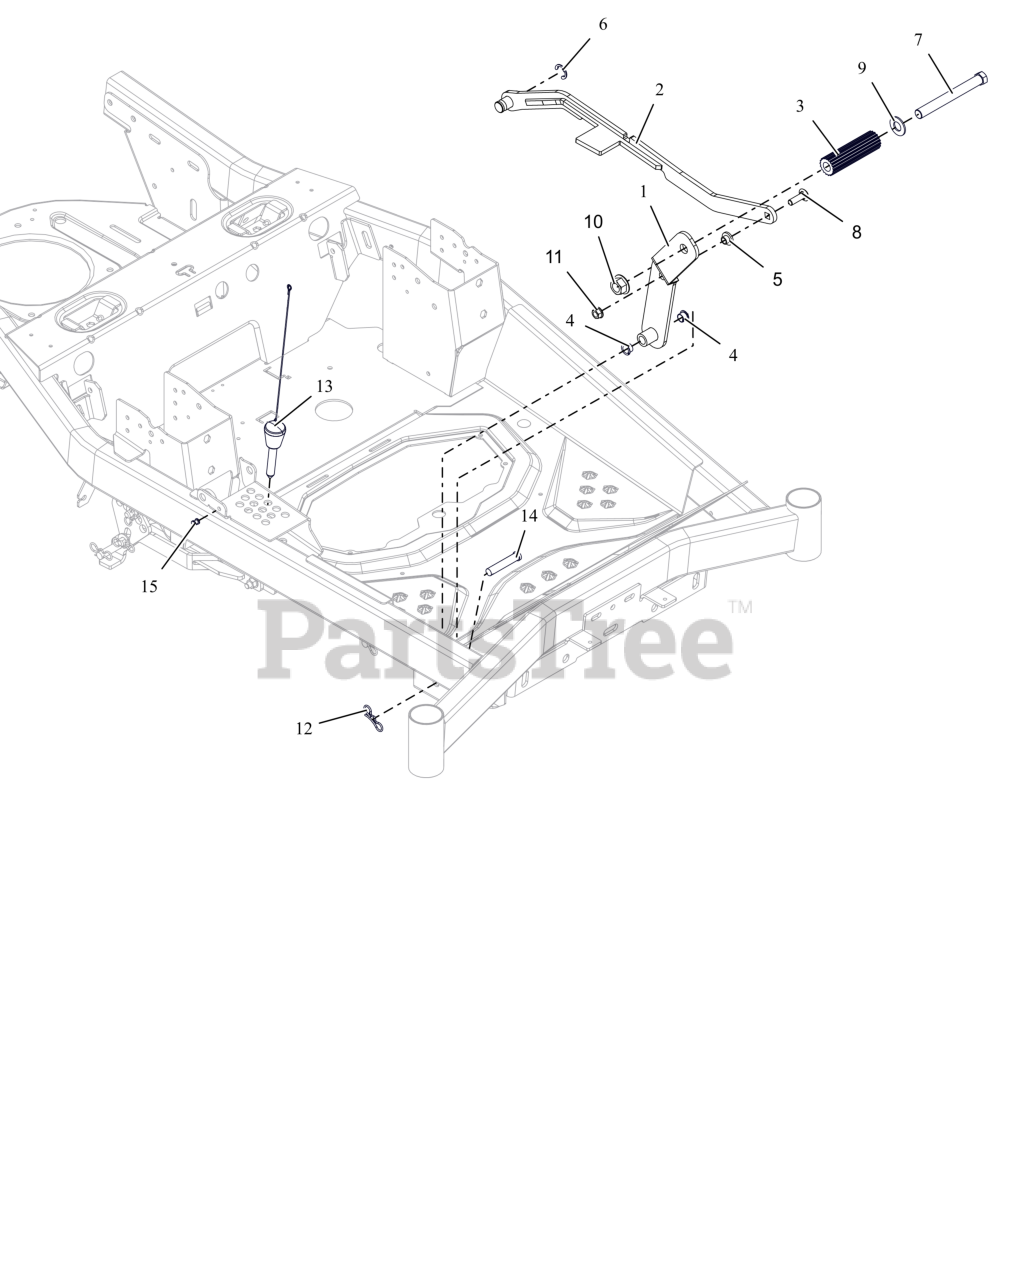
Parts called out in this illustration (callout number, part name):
1	WLDMT- FOOT PEDAL-ORG
2	LINK- DECK LIFT-ORG
3	ROD, FOOT PEDAL (BLACK)
4	BUSHING, POLYLINER-.50 SPLIT
5	BSHG-FLG .385X.500X.875X.406
6	E-RING .750X.050
7	BLT, HEX .62-11X5.50 G5 FBP
8	BLT,RHSSN .38-16X1.25 G5 ZCC
9	WSHRFLT 5/8SAE CARBHARD FBP
10	NUT,FLG-TOP LK .625-11 FBP
11	NUT-LK-CTR-FLG .375-16 GF ZCC
12	PIN, BOWTIE .091X1.875 ZCC
13	PIN- MAGNETIC .50X2.70
14	PIN-CLEV .494X2.50 BRIGHT ZINC
15	POST, & SCREW, PUSH LOCK .25 X .25
